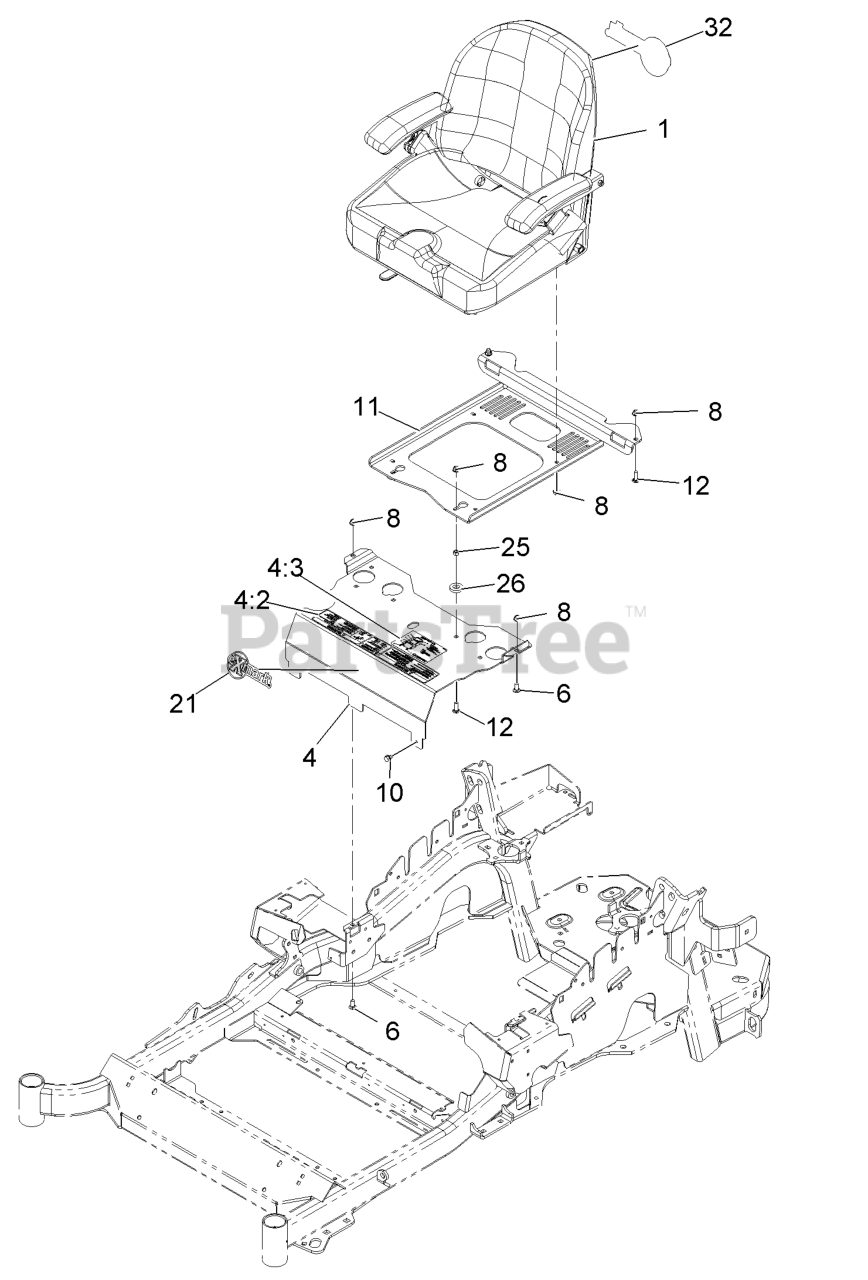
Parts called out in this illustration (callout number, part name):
4	MOUNT-SEAT
4:2	DECAL-CONSOLE
4:3	DECAL-SERVICE AID
6	SCREW-CARR
8	NUT-HF, NI
11	PLATE-SUPPORT, SEAT
12	SCREW-CARR
25	NUT-HEX
32	DECAL,EXMARK LOGO
